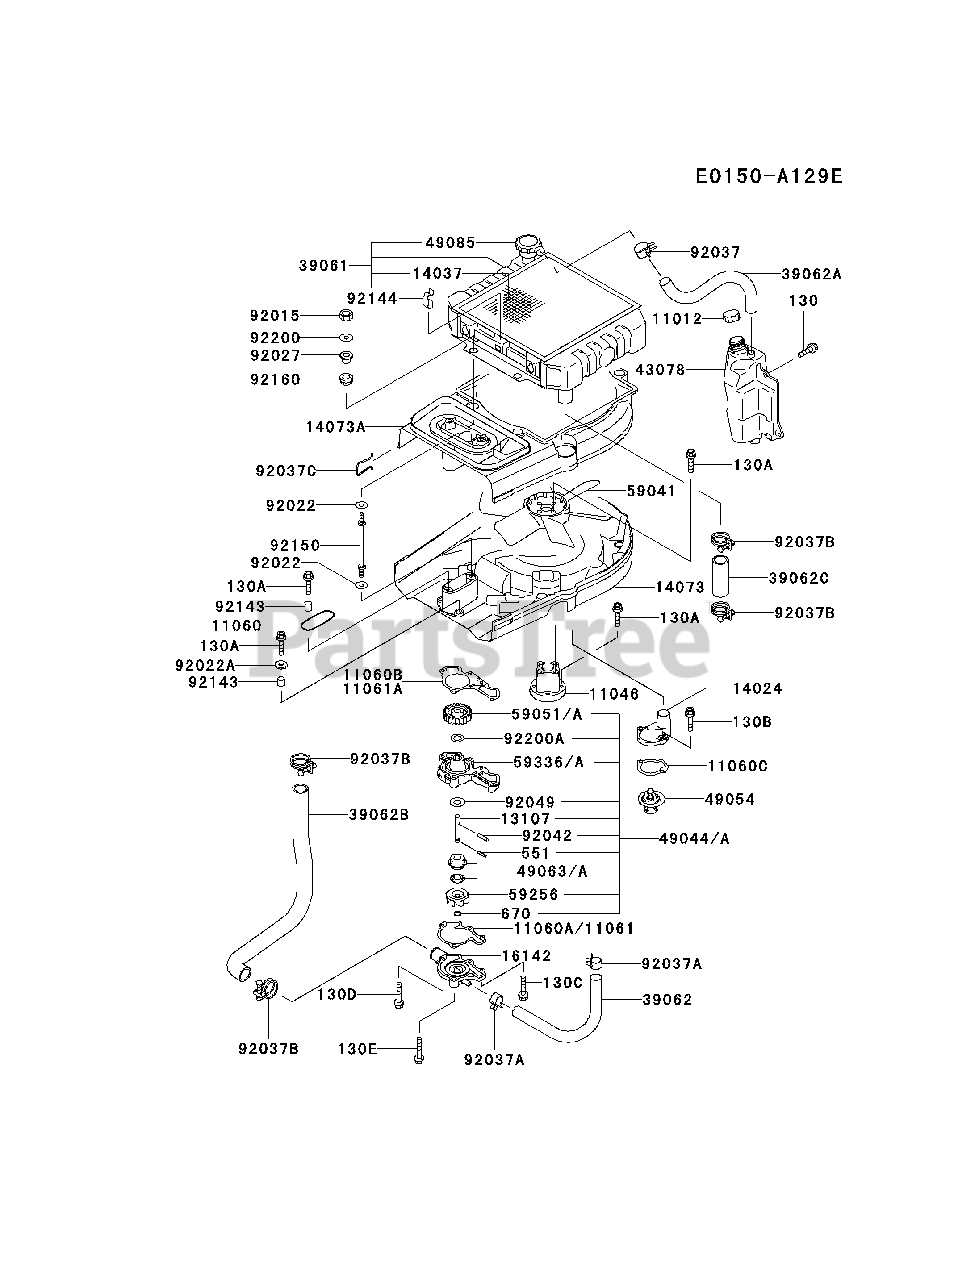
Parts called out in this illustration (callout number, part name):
130	BOLT-FLANGED
130A	BOLT-FLANGED
130B	BOLT-FLANGED
130C	BOLT-FLANGED
130D	BOLT-FLANGED
130E	BOLT-FLANGED
551	PIN-DOWEL
670	O RING
